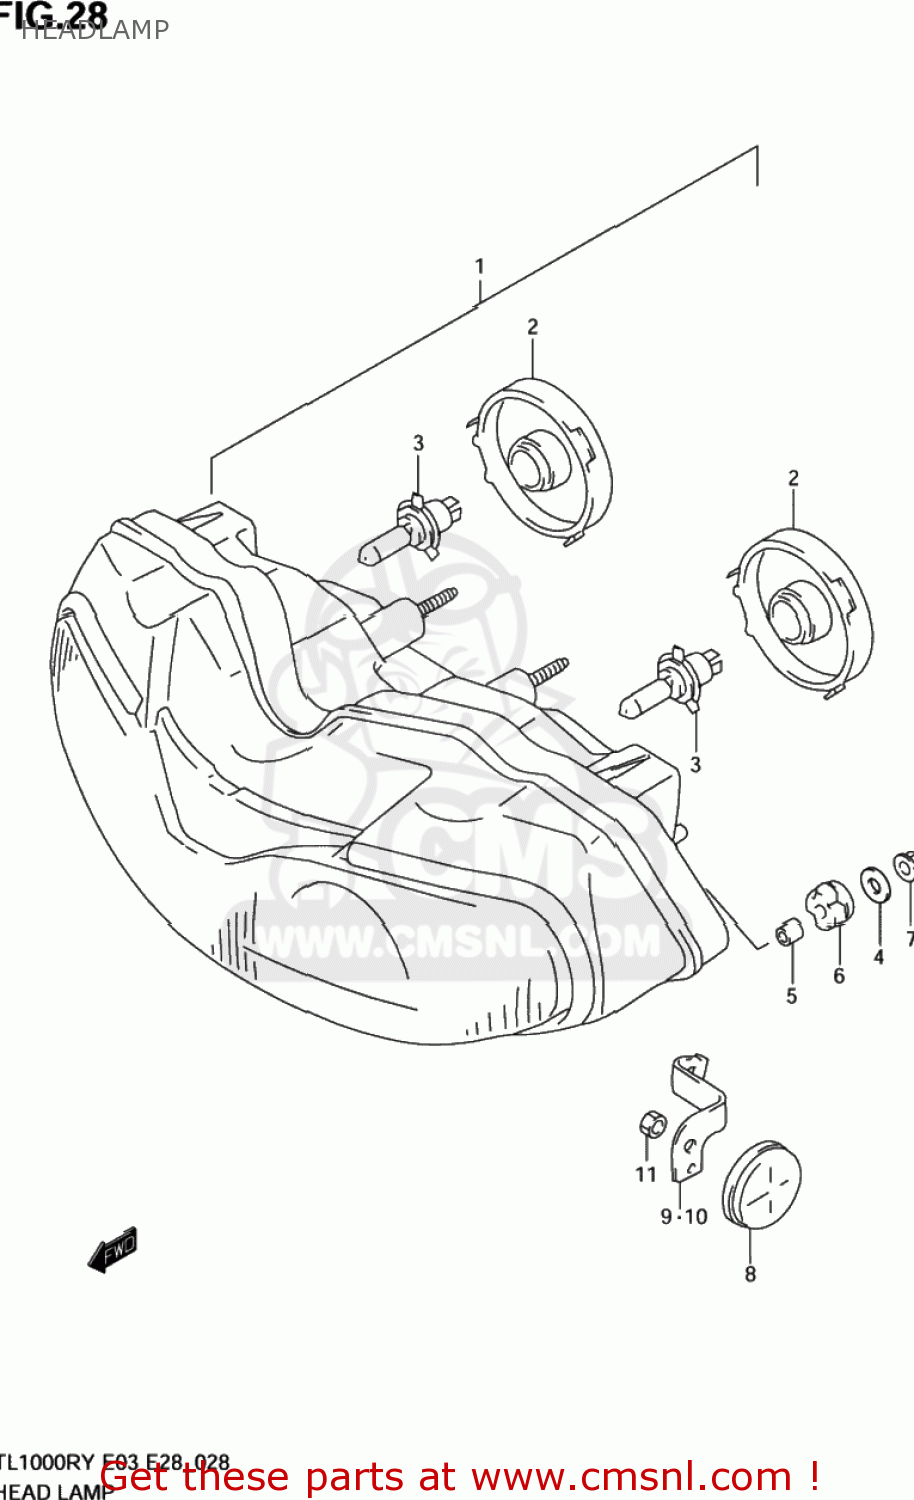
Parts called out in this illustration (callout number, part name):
1	HEADLAMP ASSEMBLY
2	COVER,SOCKET
3	BULB(12V60/55W,H4)
4	WASHER(6.5X20X1.6)
5	SPACER(6.5X9X13.5)
6	CUSHION
7	NUT
8	REFLECTOR,REFLEX FR
9	BRACKET,FR SIDE RR,R
10	BRACKET,FR SIDE RR,L
11	NUT
